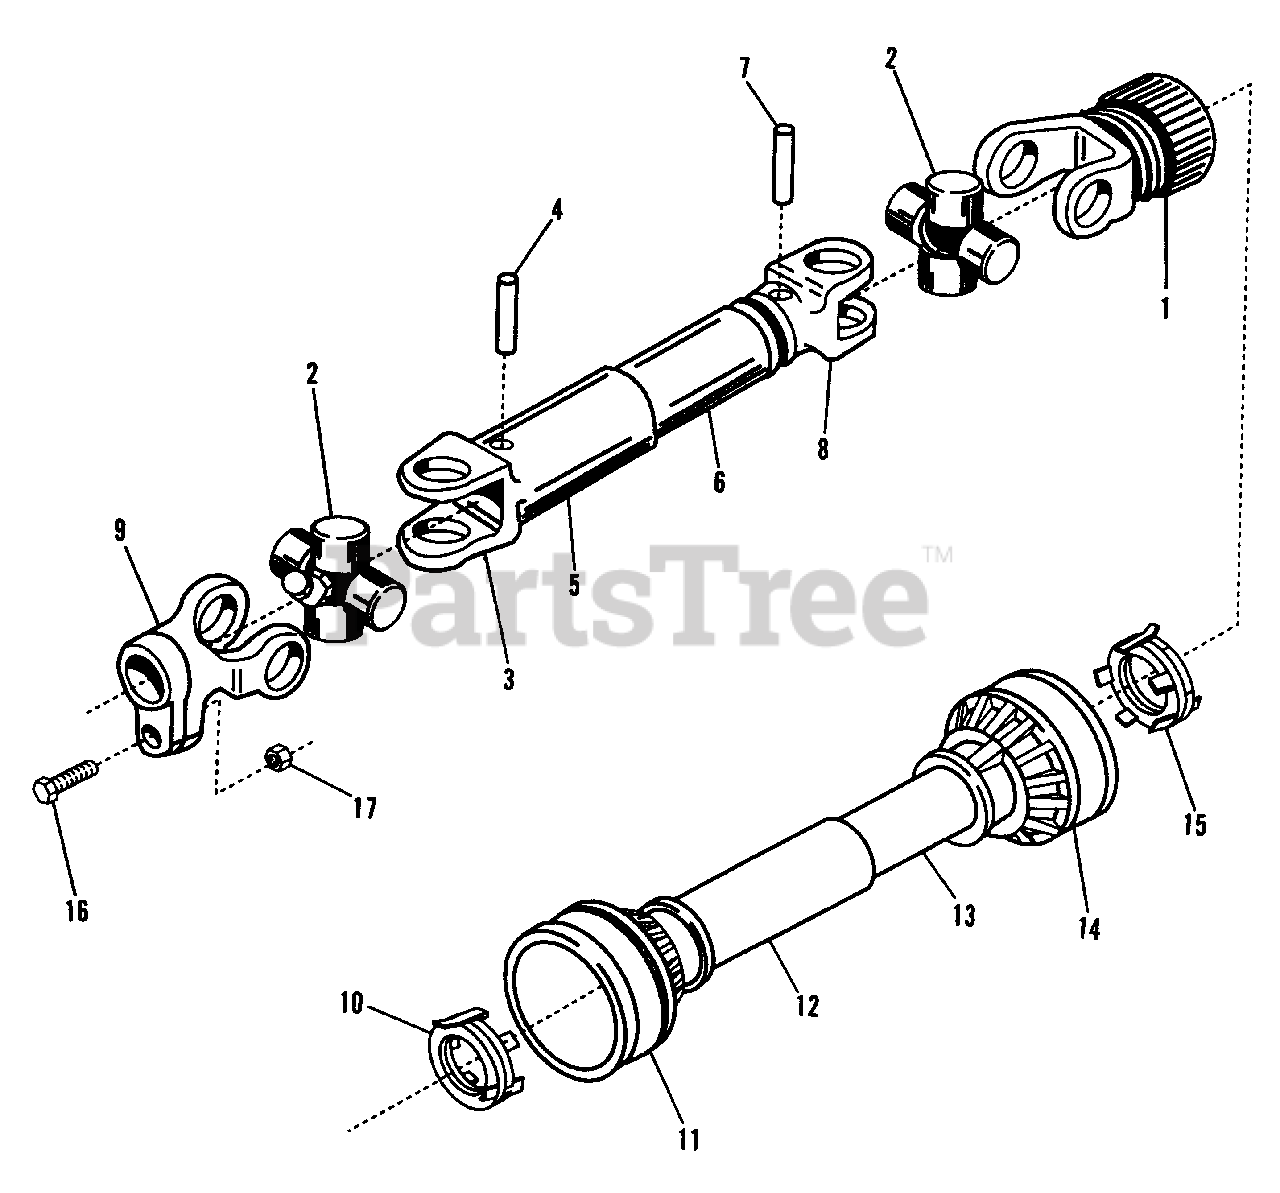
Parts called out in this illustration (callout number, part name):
3	YOKE, Outer Tube
4	ROLL PIN, 8 x 55mm
7	ROLLPIN, 8 x 45mm
8	YOKE, Inner Tube
9	TORQUE LIMITER
10	OUTER BEARING SHIELD
12	OUTER SHIELD TUBE
13	INNER SHIELD TUBE
15	INNER BEARING SHIELD
16	BOLT, Shear, M06-1 x 40mm, CL 8.8
17	NUT, Hex, Nyloc, M06-1
